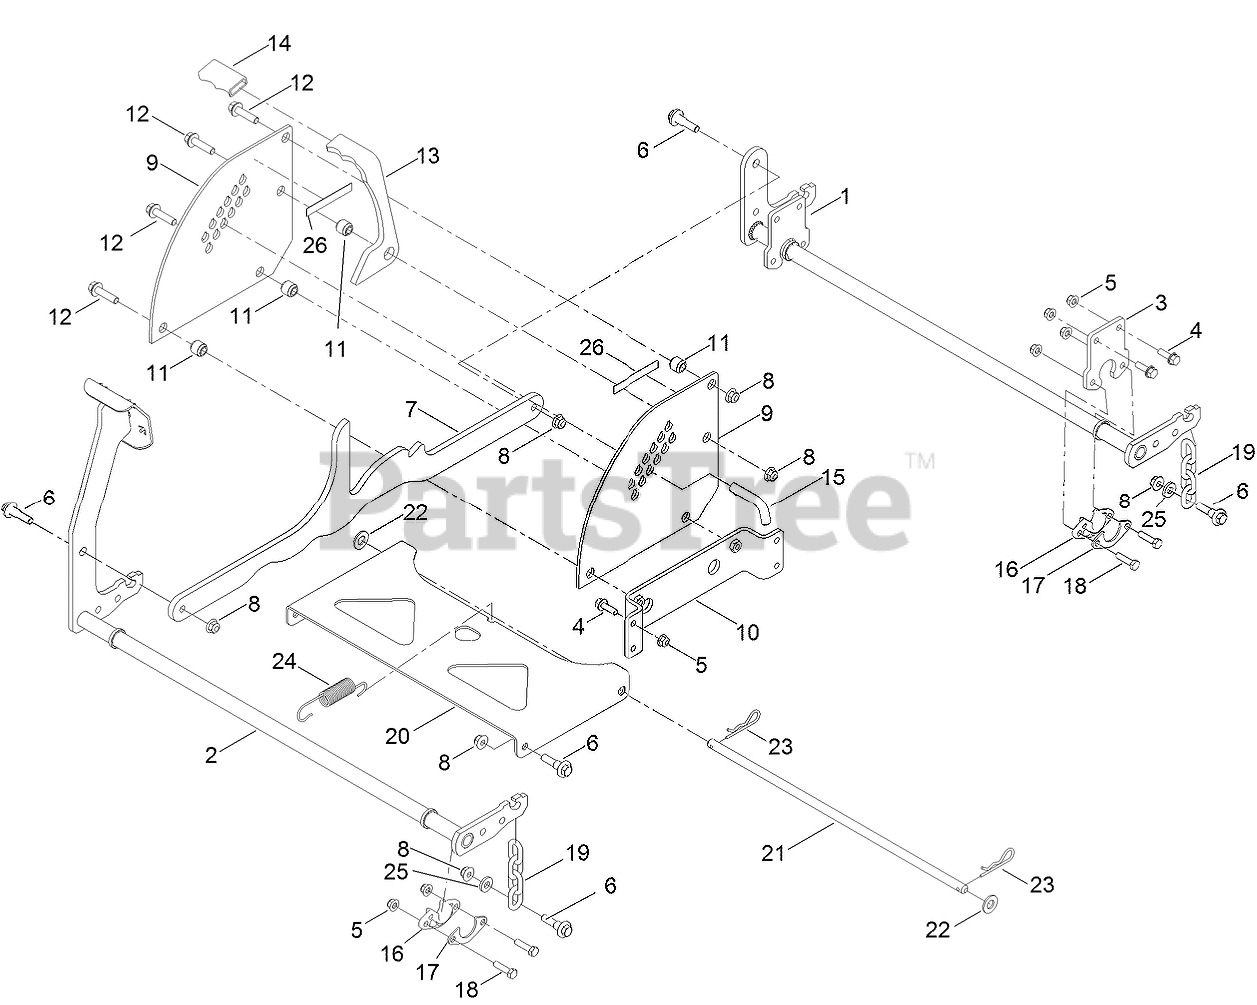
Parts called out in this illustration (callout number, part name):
1	PIVOT-REAR
2	PIVOT-FRONT
4	SCREW-HHF
5	NUT-HF, NI
6	BOLT-SHOULDER
7	LINK-HOC
8	NUT-HF, NI
9	PLATE-DECK, LIFT
10	PLATE-LIFT
11	SPACER-STEP, DOUBLE
12	SCREW-HHF
13	LOCK-TRANSPORT, HOC
14	GRIP-FLAT
15	PIN-HOC
16	BUSHING-FLANGE
17	GUSSET-LIFT, DECK
18	SCREW-HH
19	CHAIN-DECKLIFT
20	PAN-PIVOT, DECK
21	ROD-PIVOT, DECK
22	WASHER-FLAT
23	PIN-COTTER
24	SPRING-EXTENSION
25	SPACER
26	PAD-RUBBER
